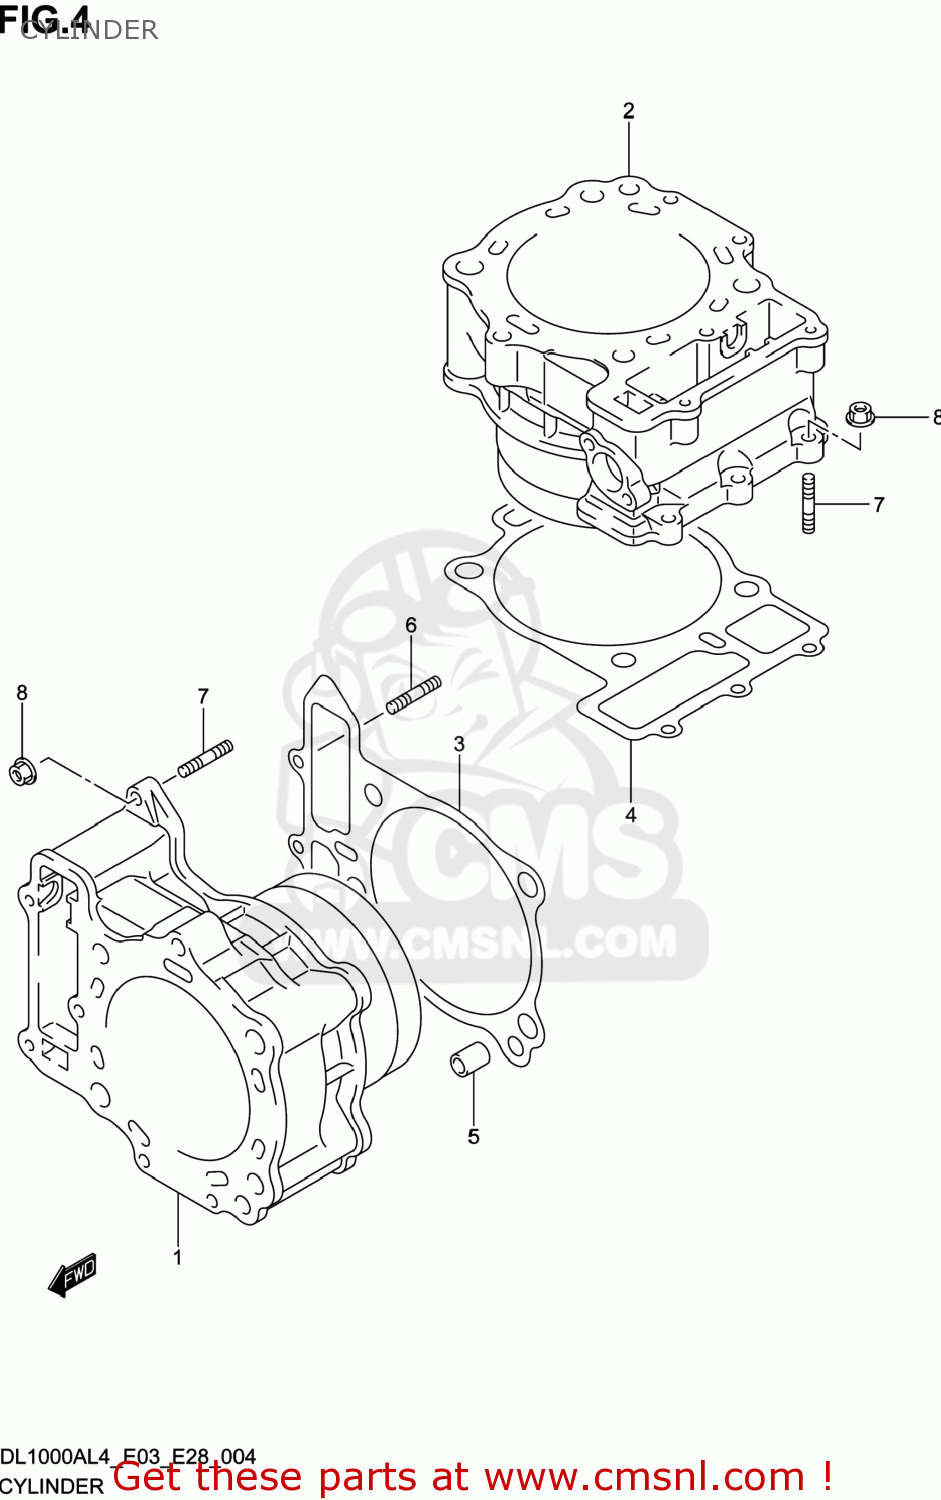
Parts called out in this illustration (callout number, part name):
1	CYLINDER,FRONT
2	CYLINDER,REAR
3	GASKET,CYLINDER FRONT (NAS)
4	GASKET,CYLINDER REAR (NAS)
5	PIN
6	BOLT,STUD
7	BOLT,STUD
8	NUT
